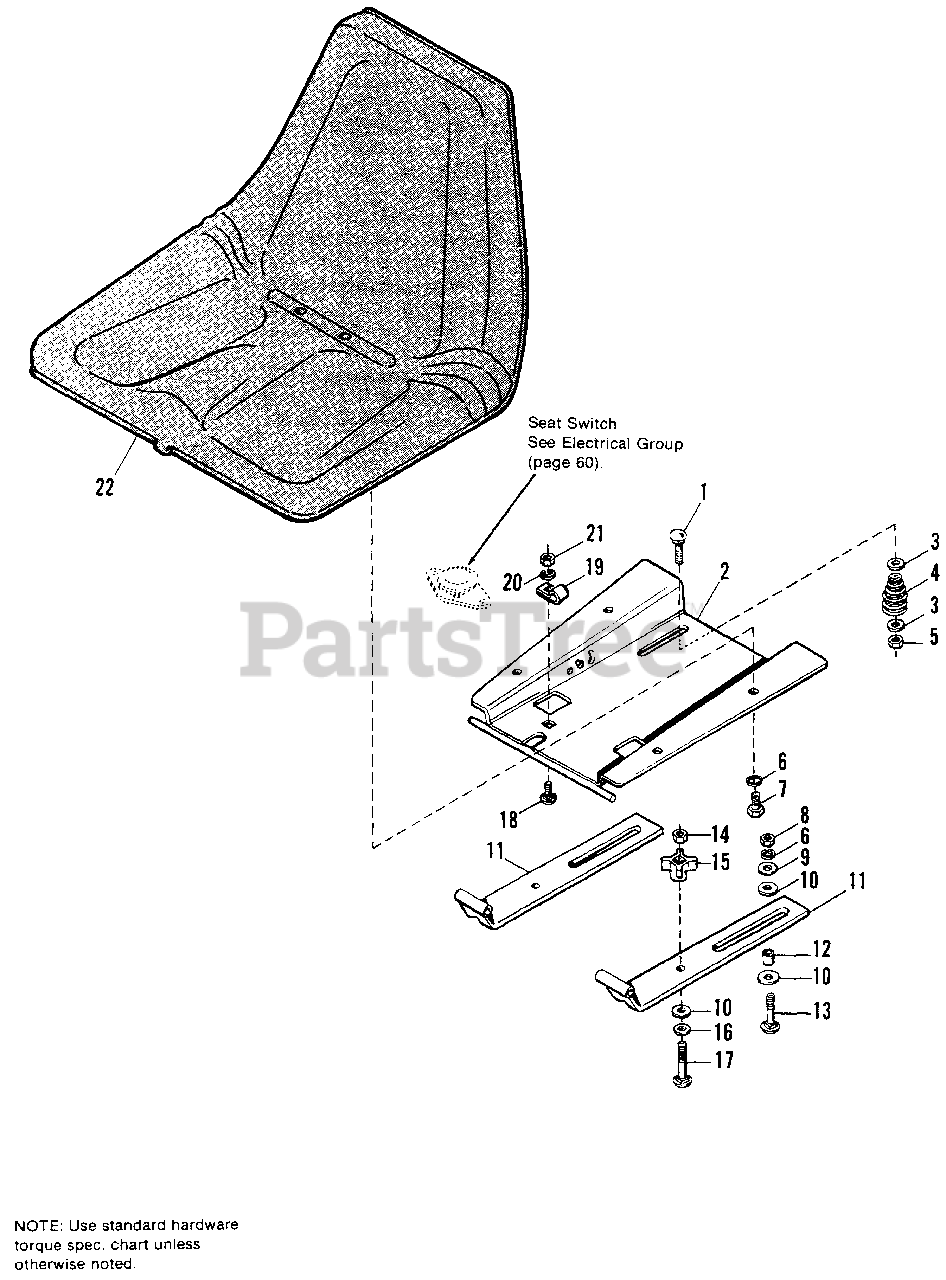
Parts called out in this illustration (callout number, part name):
1	BOLT, Carriage, 5/16-18 x 1-1/4, Gr. 5
2	HINGE & PIVOT ASSY., Upper Seat
3	WASHER, Plain, 21/64 I.D. x 1-1/4 O.D. x 14 Ga.
4	SPRING, Seat
5	NUT, Centerlock, Flange, Large Whiz, 5/16-18
6	LOCKWASHER, 5/16
7	CAPSCREW, Hex Hd., 5/16-18 x 5/8, Gr. 5
8	NUT, Hex, 5/16-18
9	WASHER, Flat, 11/32 x 1 x 1/8
11	HINGE ASSY., Lower Seat
12	SPACER, Seat Hinge
13	BOLT, Carriage, 5/16-18 x 1, Gr. 5
14	NUT, Centerlock, 5/16-18
16	NUT, Push On
17	BOLT, Carriage, 5/16-18 x 2-1/4
18	BOLT, Carriage, 1/4-20 x 3/4, Gr. 5
19	CLAMP, Closed
20	LOCKWASHER, 1/4
21	NUT, Hex, 1/4-20
